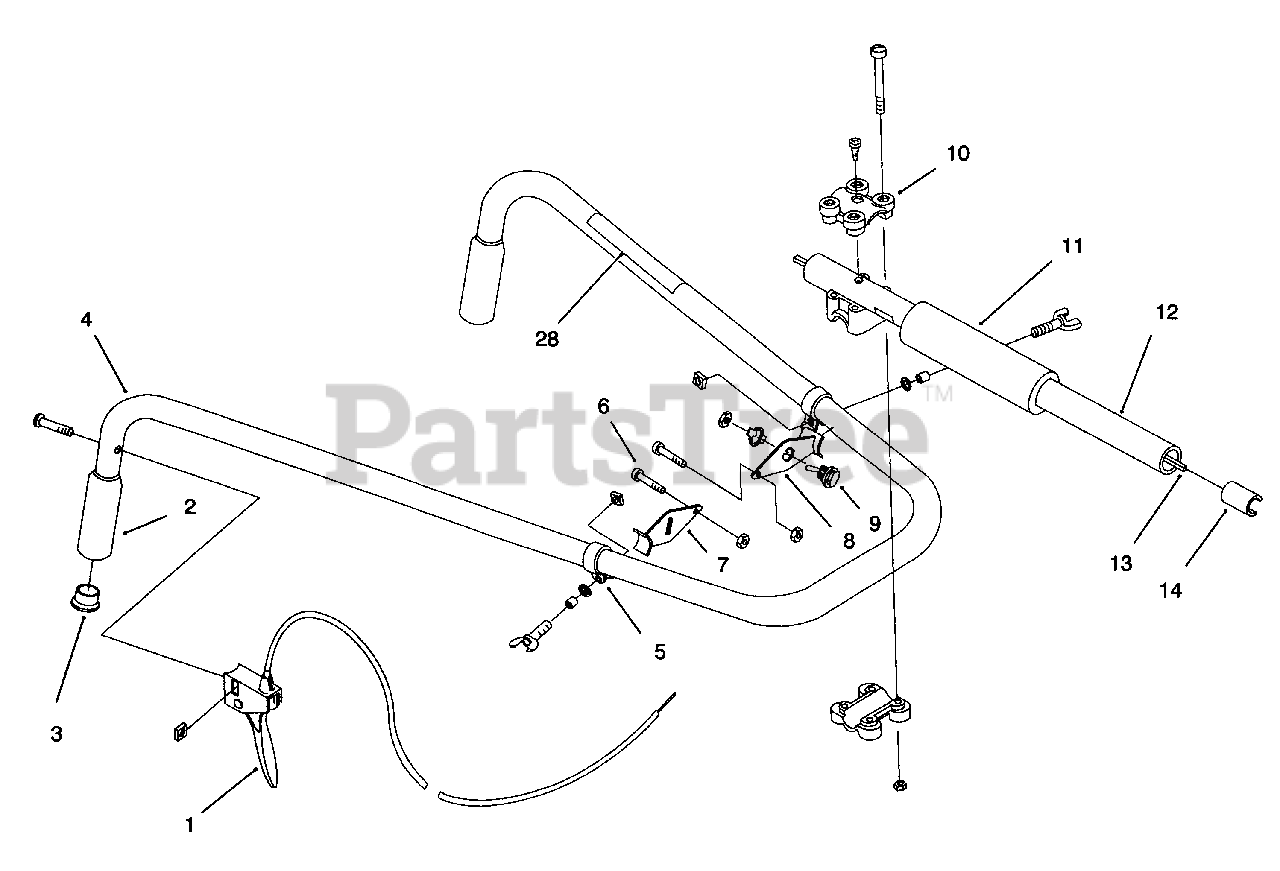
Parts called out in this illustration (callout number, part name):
1	Throttle Asm.
3	Tube Closure
4	Handle Bar
5	Clamp Asm.
6	Engine Bracket Mounting Hardware
7	Engine Mount Bracket, R.H.
8	Engine Mount Bracket, L.H.
9	Switch Asm.
10	Handle Bracket Asm.
12	Drive Shaft Housing Asm.
13	Flexible Drive Shaft
14	Retainer Sleeve
28	Decal-Safety Symbols
